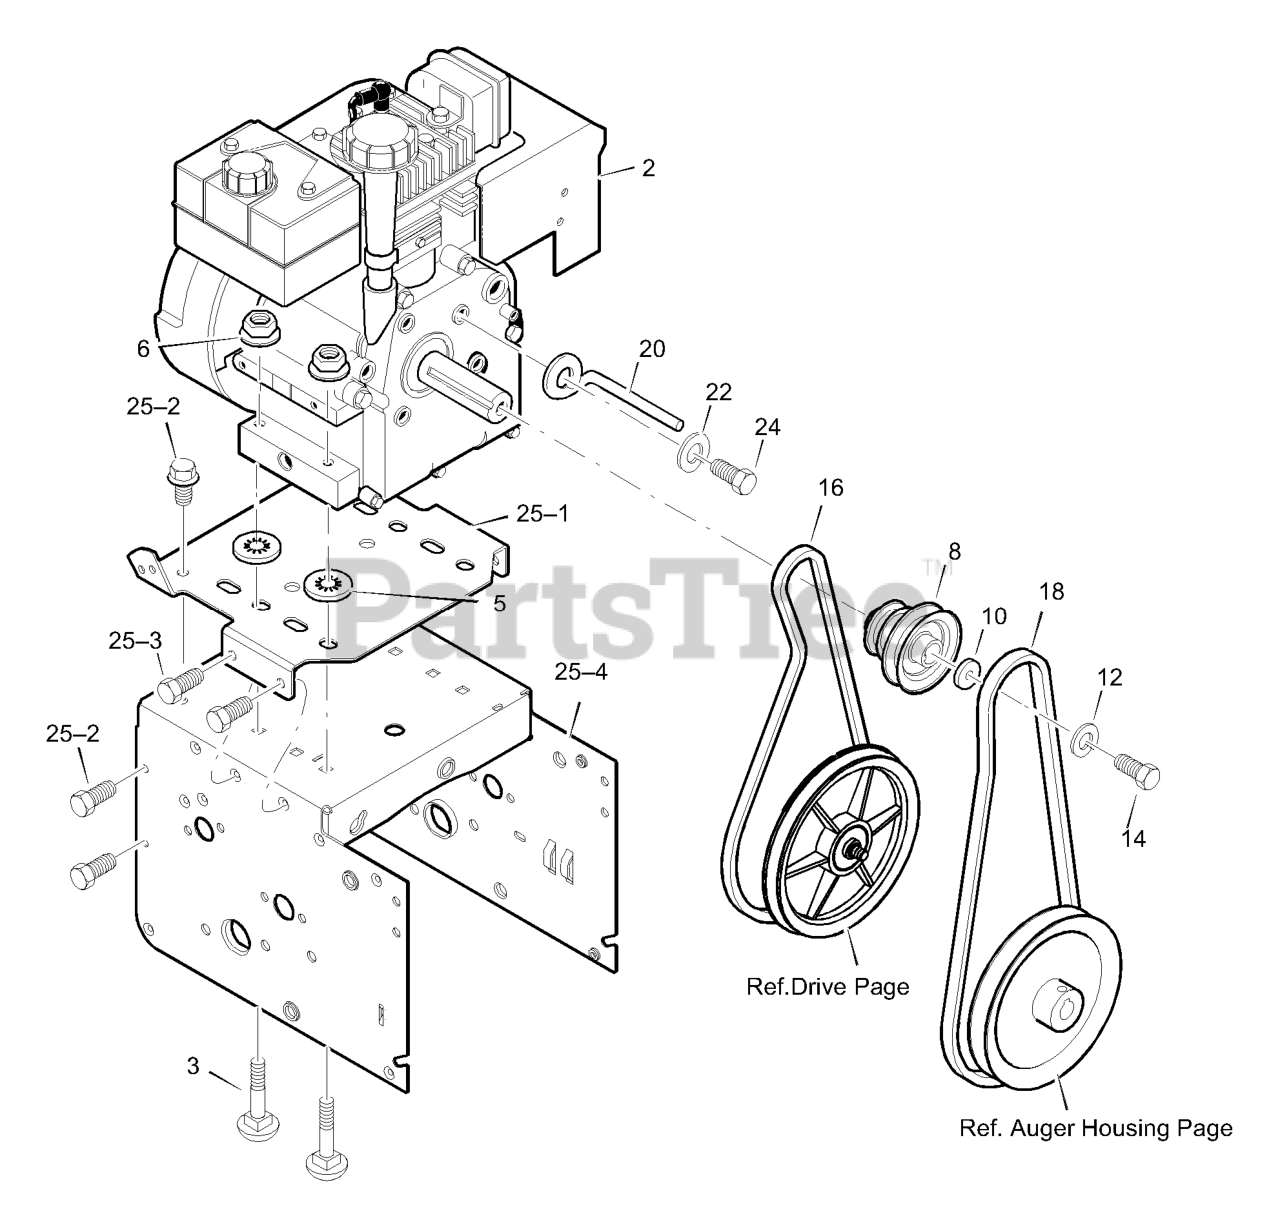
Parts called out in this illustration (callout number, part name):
2	ENGINE
3	BOLT, CARRIAGE 5/16-18
5	RETAINER, PUSH
6	NUT 5/16-18
8	PULLEY, ENGINE
10	WASHER
12	WASHER .38ID
14	SCREW, 3/8-24 x 1.00
16	BELT, V
18	BELT, V 4L
20	GUIDE, BELT
22	WASHER .31X.58X.08
24	SCREW, 5/16-24 x 0.75
25-1	PLATE, ENGINE MOUNT
25-2	SCREW, TAP 1/4-20 X .63
25-3	SCREW, TAP 5/16-18 X .50
25-4	FRAME, MOTOR BOX
